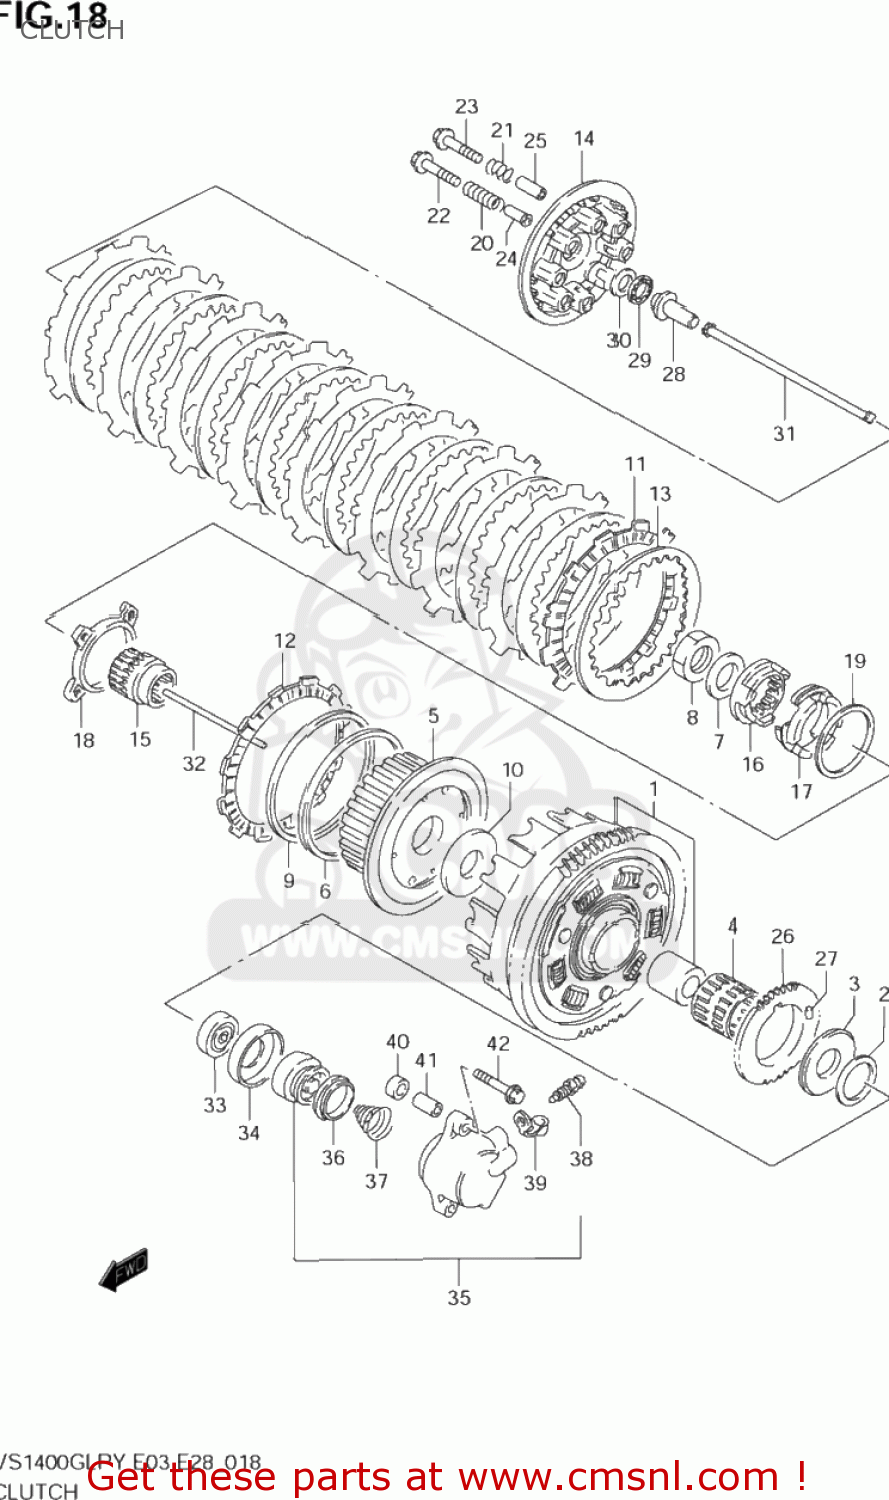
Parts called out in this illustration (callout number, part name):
1	GEAR ASSY,PRI DRIVEN
2	WASHER(25X38X2.5)
3	WASHER(25X54X2.5)
4	BEARING(35X40X35.8)
5	HUB,CLUTCH SLEEVE
6	SEAT,WAVE WASHER(T:1.4)
7	WASHER
8	NUT
9	WASHER
10	WASHER(25X60X2.5)
11	PLATE,CLUTCH DRIVE (NAS)
12	PLATE,CLUTCH DRIVE(T:3.5) (NAS)
13	PLATE,CLUTCH DRIVEN (NAS)
14	DISC,CLUTCH PRESSURE
15	SPACER,CLUTCH SLEEVE HUB
16	CAM,CLUTCH NO.1
17	CAM,CLUTCH NO.2
18	SLIDER,CLUTCH SPRING
19	WASHER(54X62X1)
20	SPRING
21	SPRING
22	BOLT(6X40)
23	BOLT
24	SPACER(6.4X10X22)
25	SPACER(6.5X9X24.1)
26	GEAR,OIL PUMP DRIVE
27	PIN(6X6)
28	PIECE,CLUTCH PUSH
29	BEARING(15X28X2)
30	WASHER(15.5X28X1)
31	ROD,CLUTCH PUSH,R
32	ROD,CLUTCH PUSH,L
33	SEAL,OIL(6X34X11)
34	RETAINER,CL PUSH ROD OIL SEAL
35	CYLINDER,CLUTCH RELEASE
36	CUP
37	SPRING,CLUTCH CYLINDER
38	BLEEDER
39	CAP,BLEEDER
40	SPACER(9X16X11)
41	PIN(6.4X9X23)
42	BOLT
